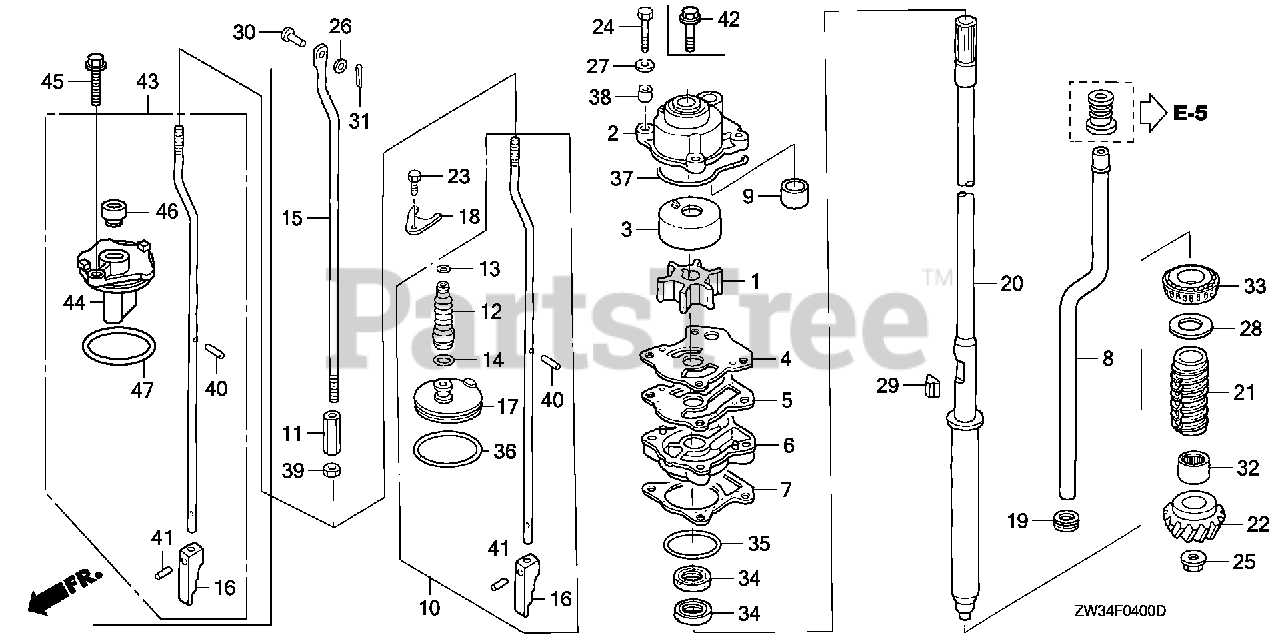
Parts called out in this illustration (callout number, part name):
1	IMPELLER, PUMP
2	HOUSING, IMPELLER
3	LINER, PUMP
4	COVER, IMPELLER
5	GASKET B, IMPELLER
6	HOUSING, WATER PUMP
7	GASKET, WATER PUMP
8	TUBE, WATER
9	RING, WATER TUBE SEAL
10	ROD, SHIFT (L)
11	JOINT, SHIFT ROD
12	GROMMET, SHIFT ROD
13	BAND A, GROMMET
14	BAND B, GROMMET
15	ROD A, SHIFT
16	ROD, PUSH
17	HOLDER, SEAL
18	PLATE, SEAL HOLDER SETTING
19	GROMMET, EXTENSION CASE
20	SHAFT, VERTICAL (L)
21	SLINGER, OIL
22	GEAR, PINION
23	BOLT, HEX. (6X12) Use up to Frame SN 1005248.
24	BOLT, HEX. (6X40)
25	NUT, SPECIAL FLANGE (12MM)
26	WASHER, PLAIN (5MM)
27	WASHER (6MM)
28	SHIM, GEAR (40X46X0.10) (A)
28	SHIM, GEAR (40X46X0.15) (B)
28	SHIM, GEAR (40X46X0.30) (C)
28	SHIM, GEAR (40X46X0.50) (D)
29	KEY, WOODRUFF
30	PIN (5X17)
31	PIN, COTTER (1.6MM)
32	BEARING, NEEDLE (7/8X11/8X1)
33	BEARING (25X47X15)
34	SEAL, WATER (17X30X7)
35	O-RING (41.7X3.5)
36	O-RING (47X3.1)
37	O-RING, WATER PUMP
38	COLLAR, IMPELLER HOUSING
39	NUT, HEX. (8MM)
40	PIN, SPRING (2X12)
41	ROLLER (3X14.8)
42	BOLT-WASHER (6X40)
43	ROD, SHIFT (L)
44	HOLDER, SEAL
45	BOLT, FLANGE (6X20) (ENGINE NO.)
46	SEAL, WATER (7MM)
47	O-RING (47X3.1)
